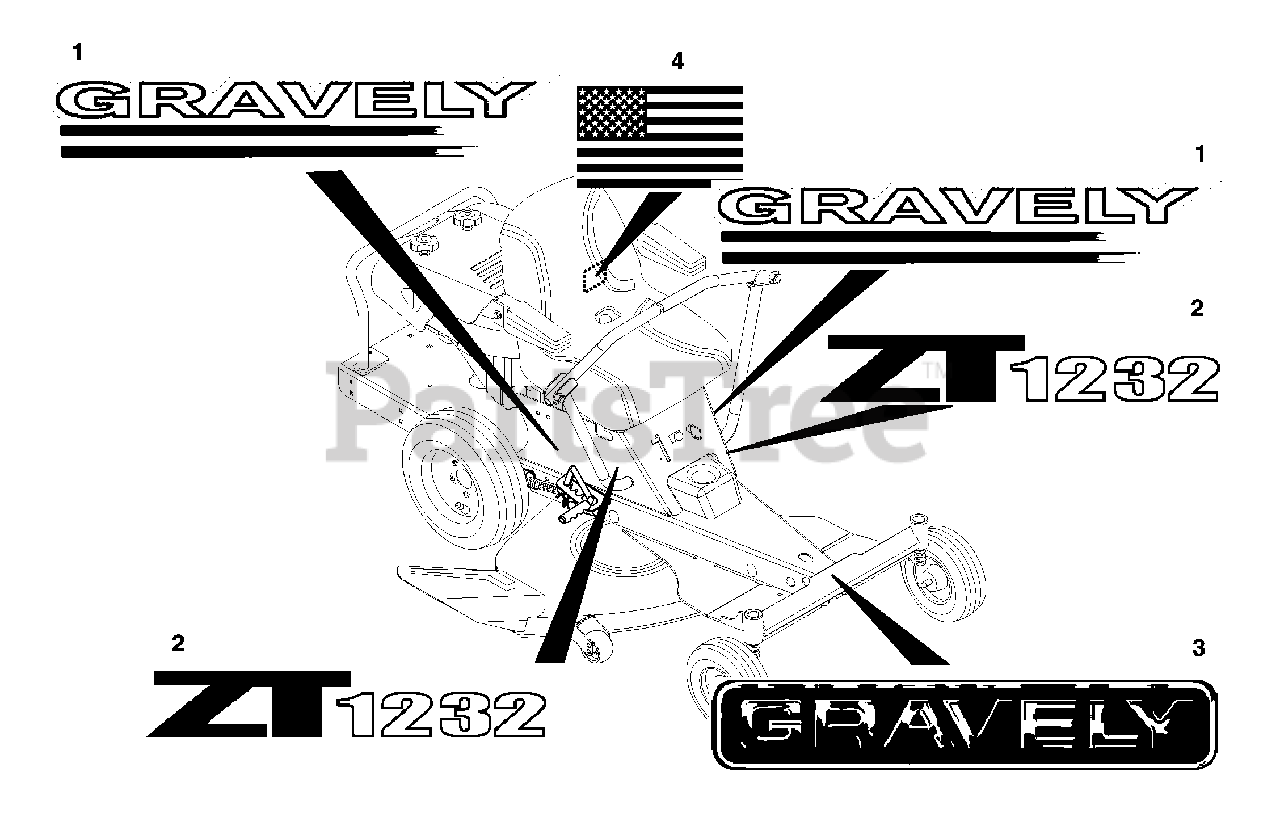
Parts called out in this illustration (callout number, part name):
1	Decal, Gravely ZT
2	Decal, Gravely 1232 (030)
3	Decal, Gravely
4	Decal, American Flag
